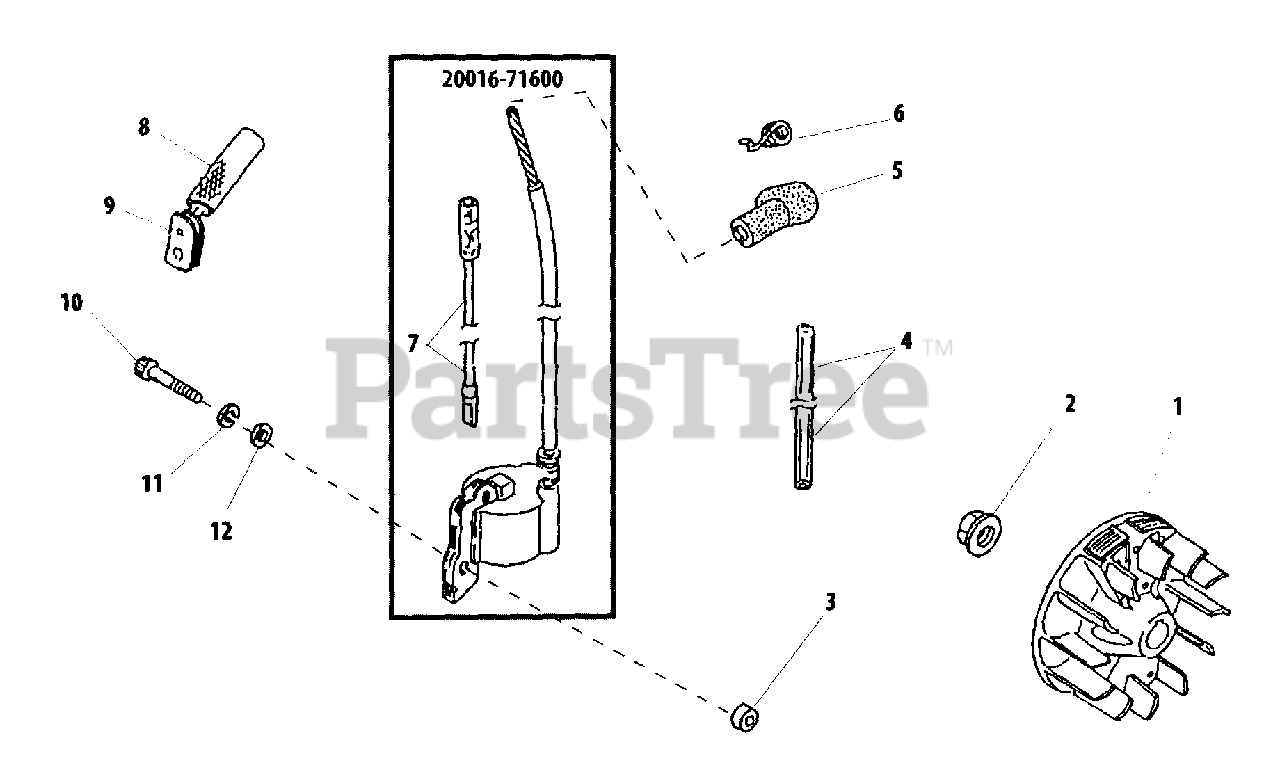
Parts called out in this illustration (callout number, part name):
1	FLYWHEEL
2	NUT - 8
3	INSULATOR
4	TUBE
5	CAP, SPARK PLUG
6	TERMINAL, SPARK PLUG CAP
7	LEAD - IGNITION
8	TUBE
9	GROMMET
10	SCREW - 4X26
11	LOCKWASHER - 4
12	WASHER - 4
20016-71600	IGNITION COIL ASSY
